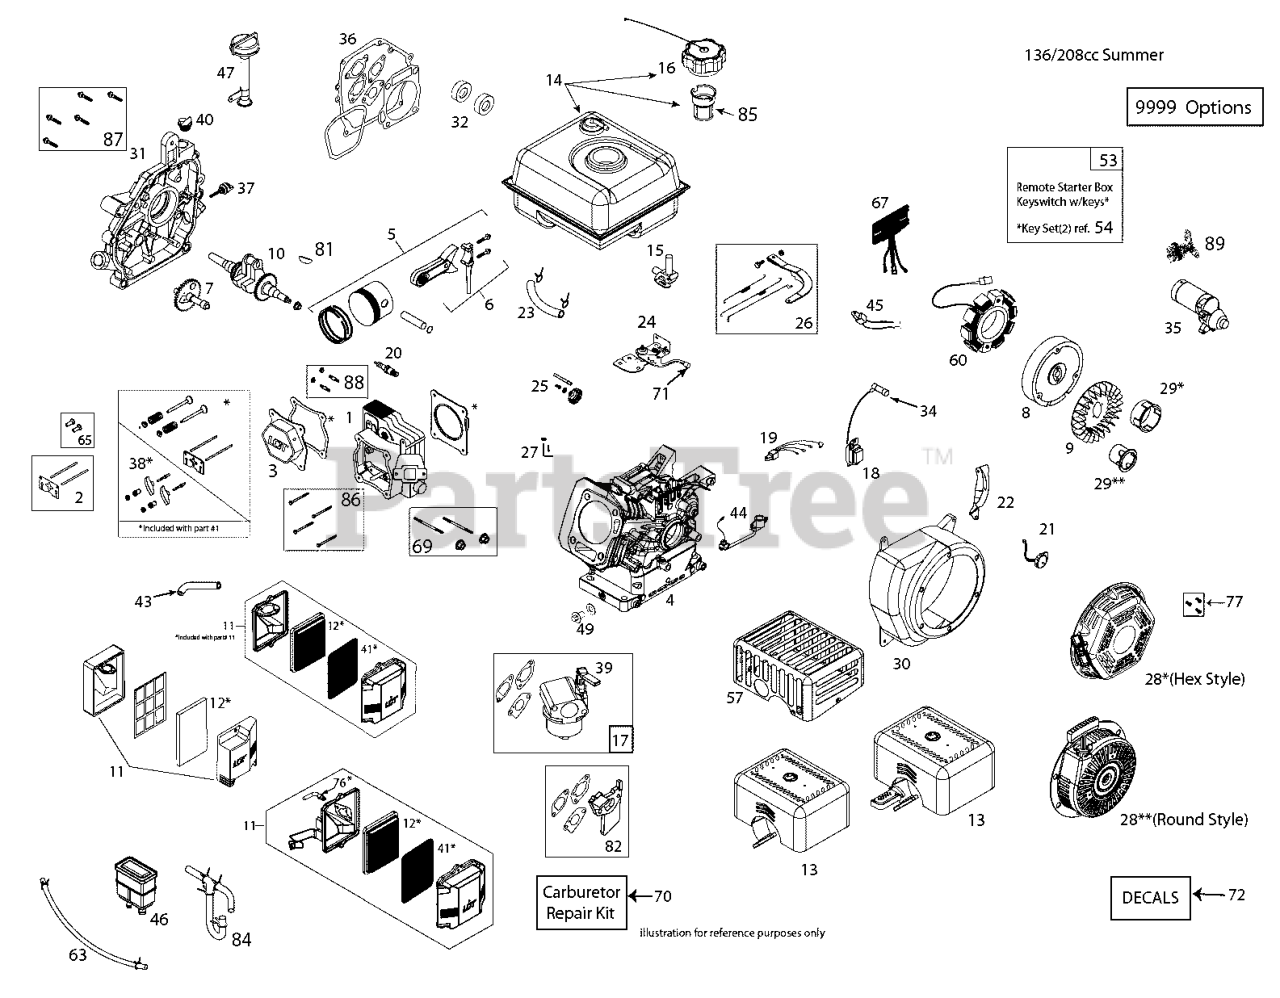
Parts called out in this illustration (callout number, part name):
1	CYLINDR.HEAD.SRV.KIT W/GASKET
2	KIT.PUSH.ROD.SRV(SK208-1001)
3	VALVE COVER ASSEMBLY
4	CYLINDER.ASM.SKSN0001.2
5	KIT.PISTON.SRV(SK208-1400)
6	KIT.CONNECT.ROD.SRV(SK208-1500
7	KIT.CAMSHAFT.208CC.LCT
8	FLYWHL.ASSY.ELECT.(SKSN0405)
9	FLYWHEEL FAN 420586
10	CRNKSHFT-KYD#14.208CCSKSNO8001
13	ASSY.MUFFLER.GENII.SKSN0201.1
14	FUEL.TK.ASSY.GENII.SKSN0311.1
15	FUEL.PETCOCK.SNOW(SKSN4900)
16	FUEL CAP OVERSIZED CLICK STYLE
17	CARB.ASSEMBLY.GEN.II.LCT.208CC
18	208CC IGN COIL (STD)
19	CDI.BOX SNOW
20	SPARK.PLUG(2083810)
21	SWITCH.ON/OFF(SKSN-0403)
23	FUEL HOSE KIT
24	SPEED.CTRL.BRKT.(SKSN0150)
25	GOVENOR.GEARS ASM(SK2082900)
26	CARBURETTOR GOVERNOR LINK.ASM.
27	KIT.GOVERNOR.CRANK(SK208-3100)
28	RECOIL.STRT.ROUND(BLK) SNOW
29	STARTER.CUP.SMALL(SKSN-0601.1)
30	BLOWER.HOUSING.ELEC.START.LCT
30	BLOWER HOUSING ASSY
31	CRANKCASE COVER ASSY
31	COVER CRANKCASE.LCT.SK2083605
32	SEAL KIT (2 PCS)
34	SPARK.PLUG.BOOT.SNW,SKSN4691.1
35	ELEC.START.GEN2.SKSN0451.1
36	GASKET.KIT.208CC(SK2084300.1)
37	DIPSTICK SMALL
38	ROCKER ARM KIT
39	CHOKE.KNOW.SNOW(SKSN4500)
40	NON REMOVABLE PLUG
41	FOAM.PRE.FILTER.LCT.208CC
43	TUBE.BREATHER.LCT.208
47	HIGH OIL FILL DIPSTICK ASSEM
47	TUBE ASSY HIGH OIL-FILL
49	KIT.OIL.DRAIN.PLUG(SK2089911
53	SWITH.KEY.ASSEM.SNOW.SINGLE.ST
54	KEY SET(2 KEYS) SKSN0407.1
65	TAPPET.KIT.LCT.208CC
69	CARB.STUDS & COUPLING KIT.SNOW
70	CARB.REPAIR.KIT.LCT.SK9900.2
77	BOLT.KIT.RECOIL.LCT.ALL.ENGINE
81	KEYS.FLYWHEEL.208/414CC.5PACK
82	SPACER.CARBURETOR.208CC.LCT
85	Husqvarna TBD
86	KIT.BOLT.CYLINDER.HEAD.(4PC)
87	KIT.BOLT.CRANKCASE.COVER.6PC
88	STUD.MUFFLER.KIT.LCT
9999	HIGH.ALTITUDE.JET 6,000FT
